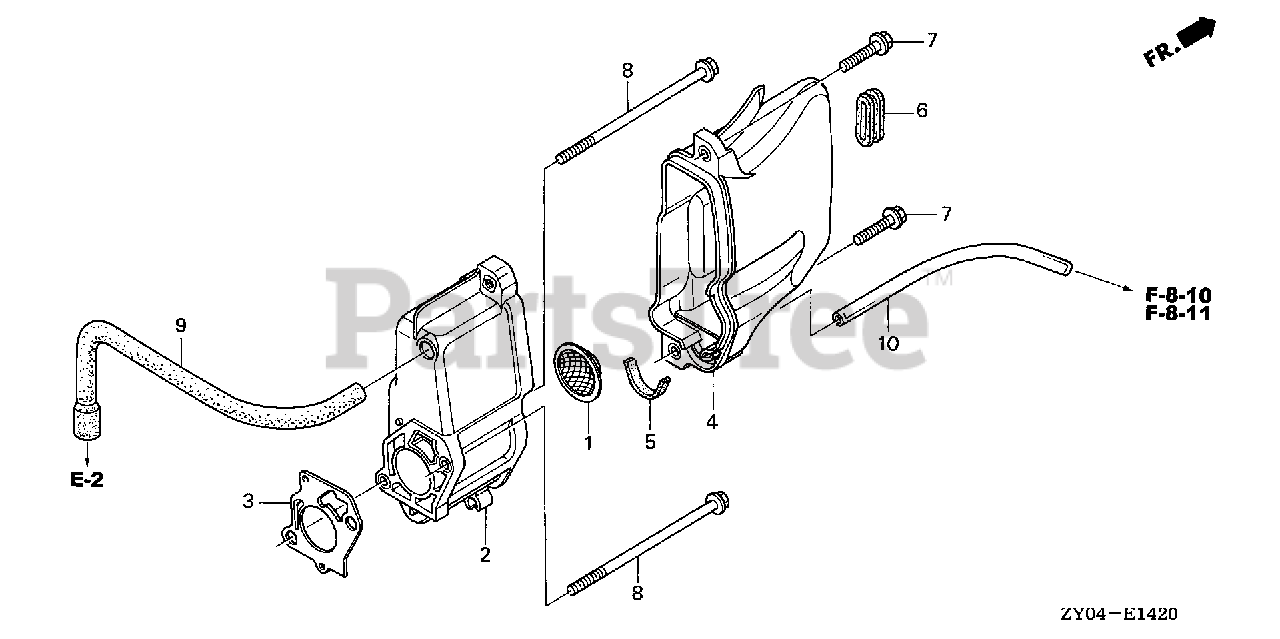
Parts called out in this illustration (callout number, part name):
1	TRAP, FLAME
2	PLATE, MUFFLER
3	GASKET, MUFFLER PLATE
4	COVER, MUFFLER
5	GASKET, MUFFLER COVER
6	RUBBER A, TANK MOUNTING
7	BOLT, FLANGE (6X22)
8	BOLT, FLANGE (6X106)
9	TUBE, BREATHER
10	BULK HOSE, VINYL (4X7X8000) (4X7X120)
